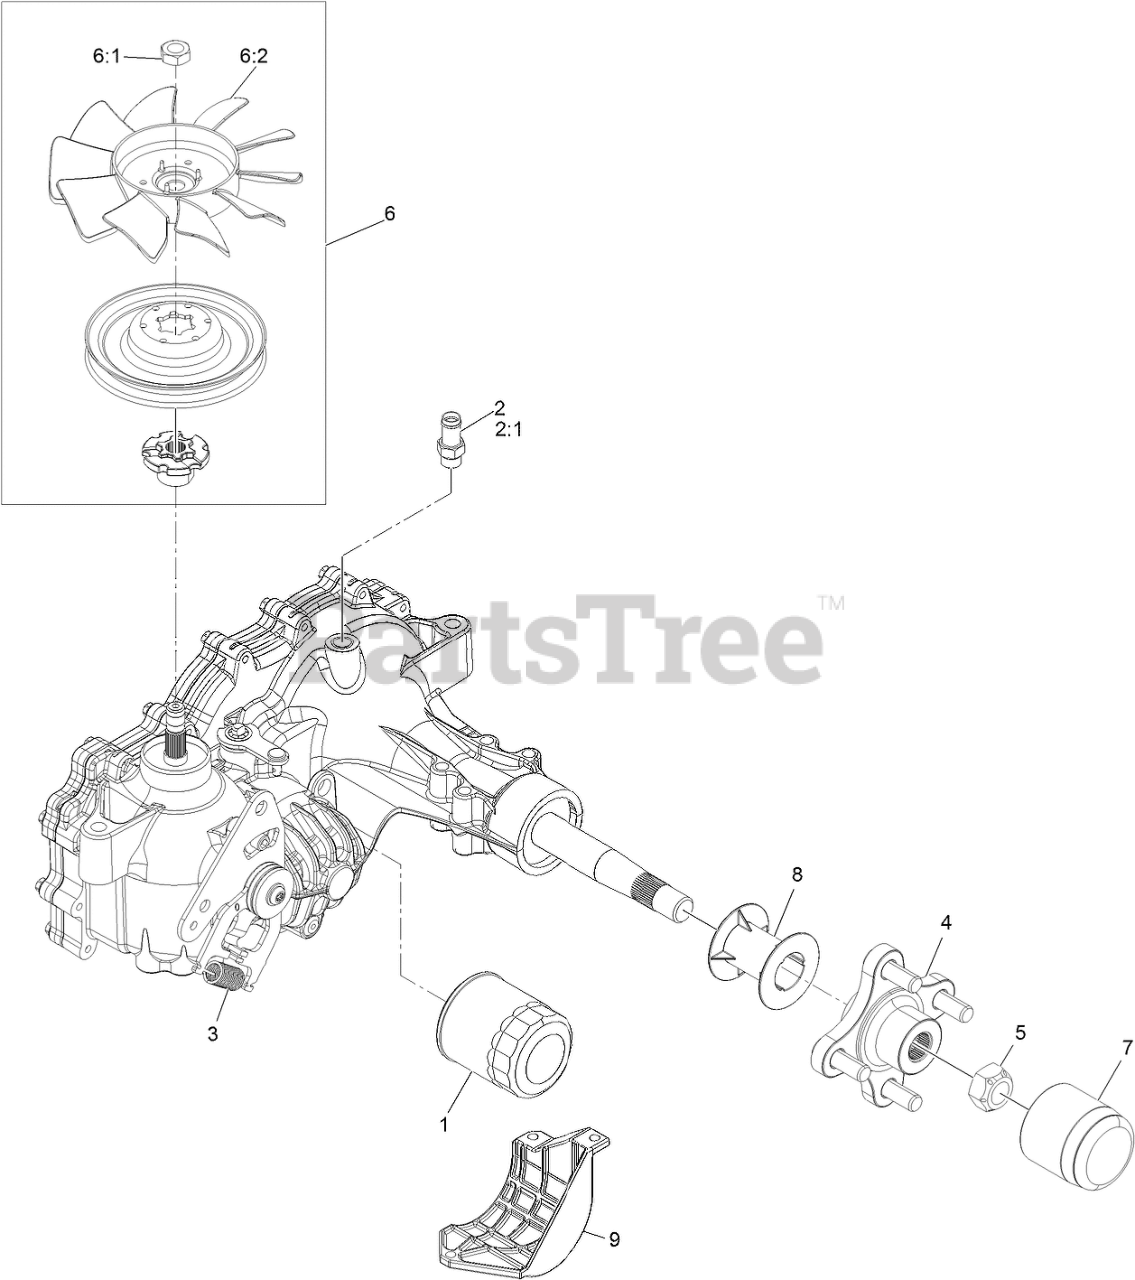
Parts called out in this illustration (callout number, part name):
1	ELEMENT-OIL FILTER, HYD
2	ADAPTER-STRAIGHT
2:1	O-RING
3	SPRING-EXTENSION
4	HUB-OFFSET
5	NUT-HUB
6	Fan And Pulley Kit
7	CAP-AXLE, LONG
8	TUBE-AXLE
9	GUARD-FILTER, LH
